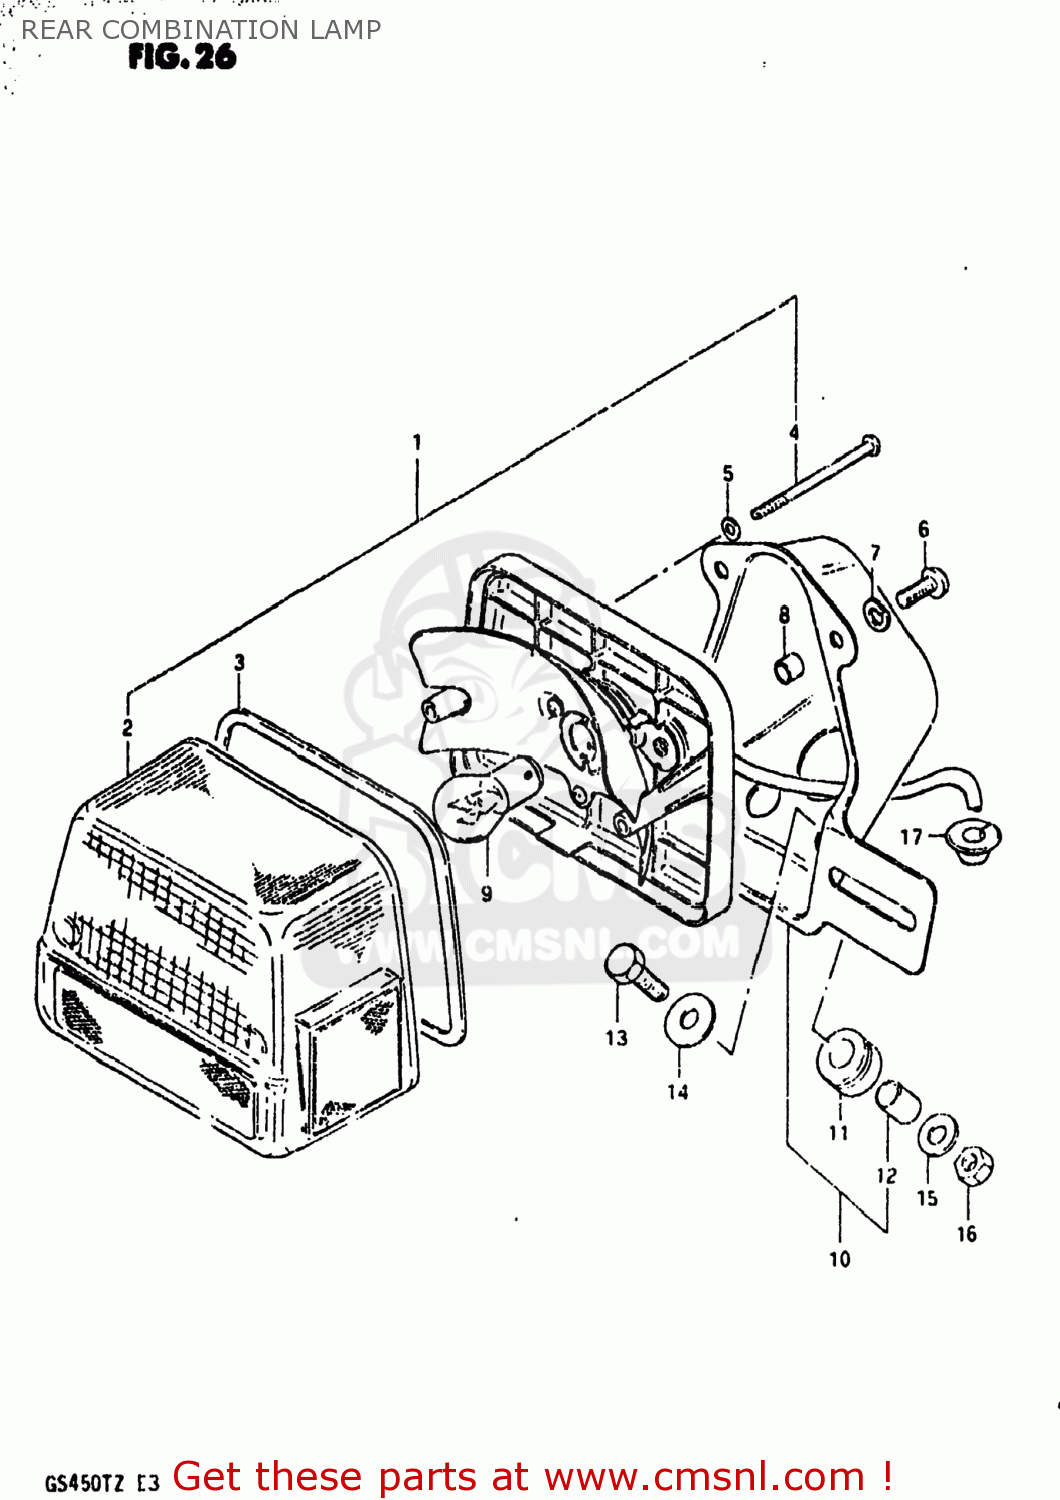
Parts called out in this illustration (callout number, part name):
1	LAMP UNIT,RR COMBNATION
2	LENS
3	GASKET (NAS)
4	SCREW
5	GASKET (NAS)
6	SCREW
7	LOCK WASHER
8	SPACER
9	BULB(12V23W)
10	BRACKET UNIT,TAIL LAMP
11	CUSHION
12	SPACER
13	BOLT
14	WASHER (6.5X20X1.2)
15	WASHER
16	NUT
17	GROMMET
